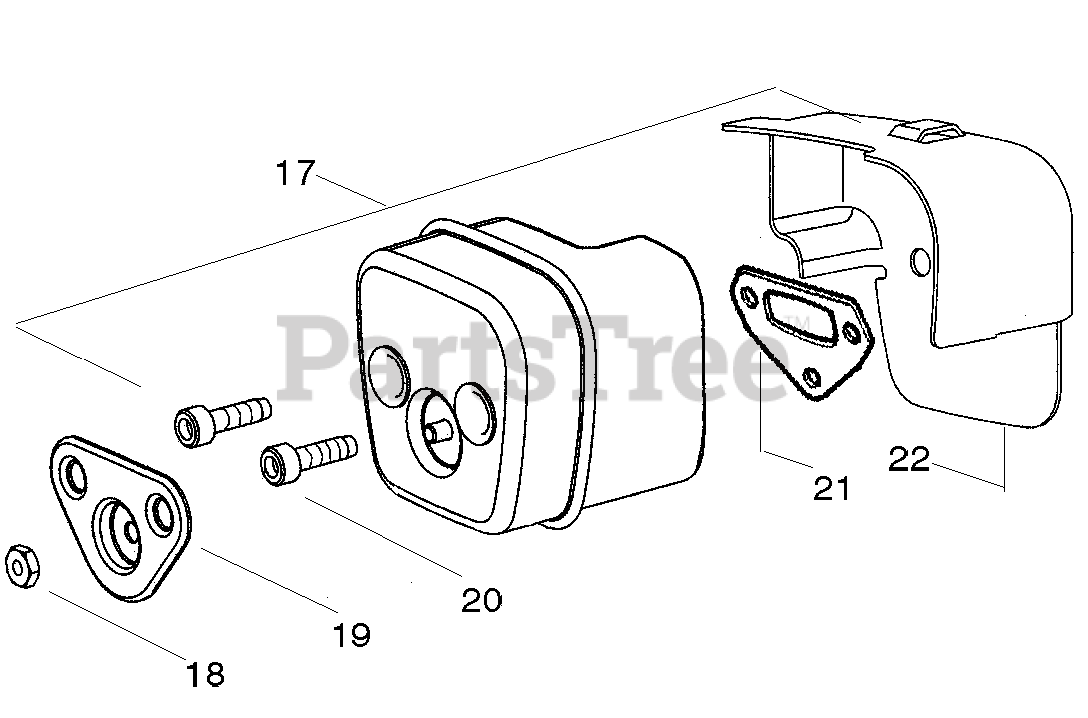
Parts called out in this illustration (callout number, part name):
17	MUFFLER KIT
18	NUT-BRASS
19	COVER BOLT
20	SCREW MUFFLER
21	GASKET-MUFFLER
22	BACKPLATE, MUFFLER
